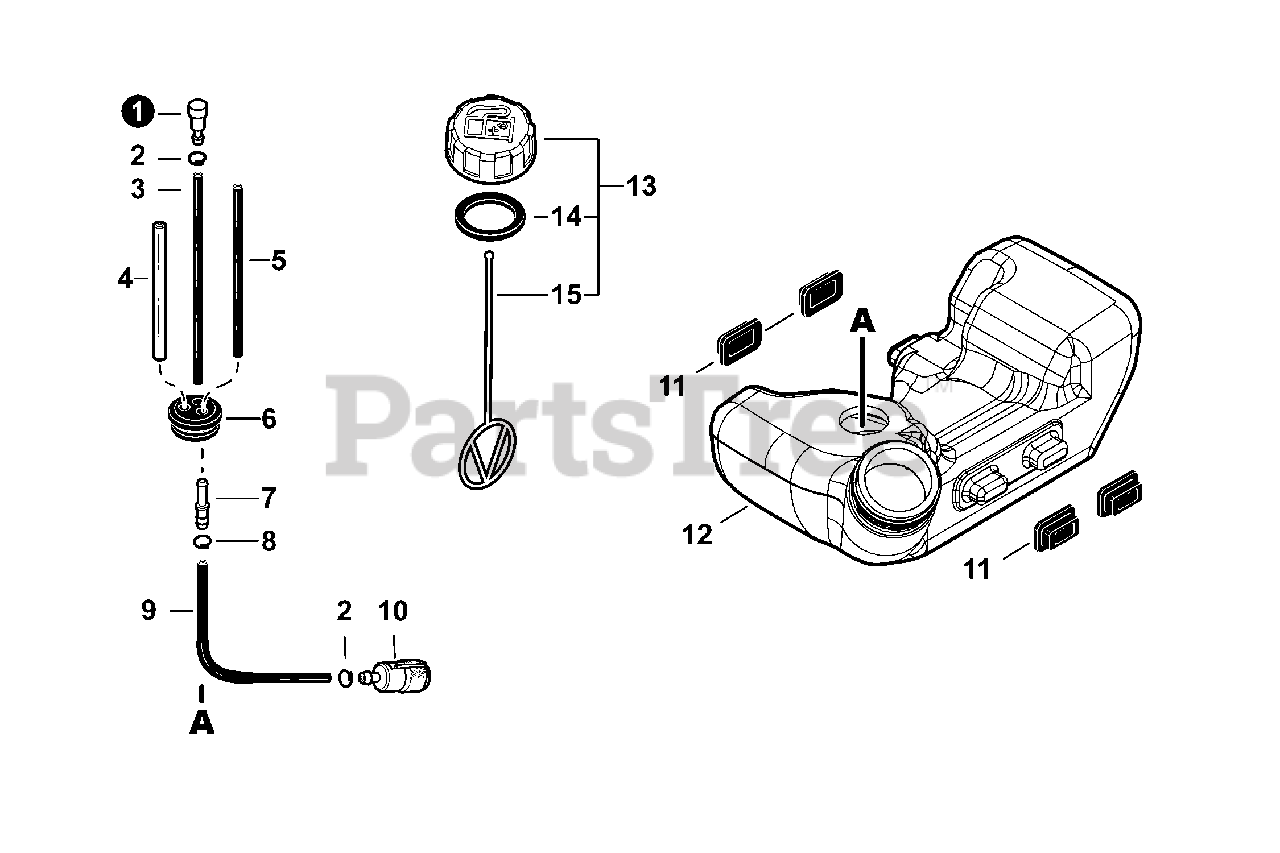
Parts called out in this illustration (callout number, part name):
1	VENT ASSY
2	CLIP Ø6
3	PIPE 3×6×90 MM
4	PIPE, FUEL 3×6×80 CLEAR
5	PIPE, FUEL 3×5×61 BLACK
6	GROMMET, FUEL
7	CONNECTOR, PIPE Ø5ר3.5
8	CLIP Ø6.5 MM
9	PIPE, FUEL 3×6×120 BLACK
10	FILTER, FUEL
11	CUSHION, FUEL TANK
12	TANK, FUEL
13	CAP ASSY, FUEL
14	GASKET, FUEL CAP
15	CONNECTOR, CAP L= 123
